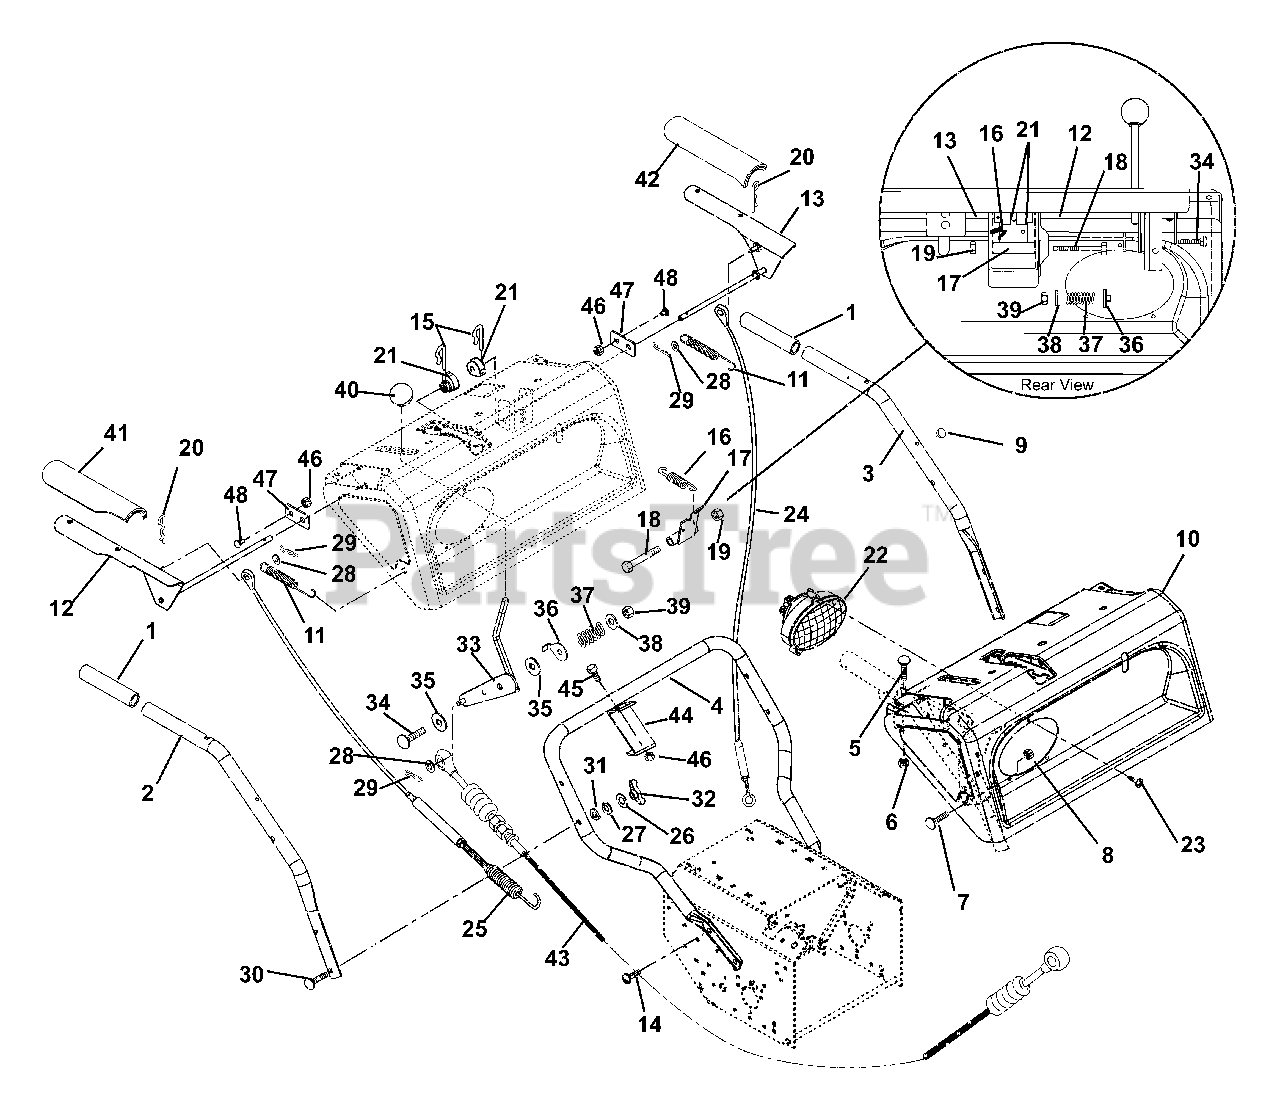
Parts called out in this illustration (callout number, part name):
1	HANDLE GRIP
2	HANDLEBAR, UPPER-RH
3	HANDLEBAR, UPPER-LH
4	HANDLEBAR, LOWER
5	BLT-RDHDXLSQNK.25-20X1.25 G5ZC
6	@NUT-LK-CTR .25-20 YWZC
7	@BLT-RDHDSQNK .31-18X1.75 G5YZ
8	@NUT-LK-CTR .31-18 YWZC
10	PANEL W/DECALS - HYBRID
11	SG-TENS .051X.50X4.87
12	LEVER, RH
13	LEVER, LH
14	BLT SERHFWH .31-18X.62 GR5YWZC
15	PIN, SPRING CLIP
16	SPRING-EXT .047X.438X1.45
17	ARM, INTERLOCK
18	@BLT-HEX .38-16X3.00 GR5 YWZC
19	@NUT-LK-CTR .38-16 YWZC
20	PIN-HAIR, ENDRIES #25 YWZC
21	CAM, INTERLOCK
22	HEADLAMP, OVAL W/ 1156 BULB
23	SCR-TAP 10-16X.75 HI-LO PPH
24	CABLE, TRACTION
25	CABLE, AUGER-HYBRID
26	@WSHR-FL-STL.38X.875X.083 YWZC
27	WSHR-LK .312X.097 HVY YWZC
28	@WSHR-FL-STL.281X.62X.065 YWZC
29	PIN-HAIR INT .06X.18X.77
30	@BLT-RDHDSQNK .31-18X2.25 G5YZ
31	WASHER,SADDLE-.320 X.937 X.062
32	KNOB - WING .312-18 UNC
33	LEVER, DEFLECTOR
34	@BLT-RDHDSQNK .38-16X2.00 G5YZ
35	FRICTION WASHER
36	FLANGE, PRESSURE
37	SG-COMP .187X.56X1.62
38	@WSHR-FL-STL.406X.812X.065 YWZ
39	@NUT-LK-CTR .38-16 YWZC
40	KNOB,BALL -BLACK 1.47" .375-16
41	GRIP, CLUTCH LEVER RH
42	GRIP, CLUTCH LEVER LH
43	CABLE, DEFLECTOR CONTROL
44	BRACKET, CHUTE CABLE
45	@BLT-HEX .25-20X1.50 GR5 YWZC
46	@NUT-LK-CTR .25-20 YWZC
47	BRACKET, RETAINING
48	@BLT-RDHDSQNK .25-20X.50 G5YZ
